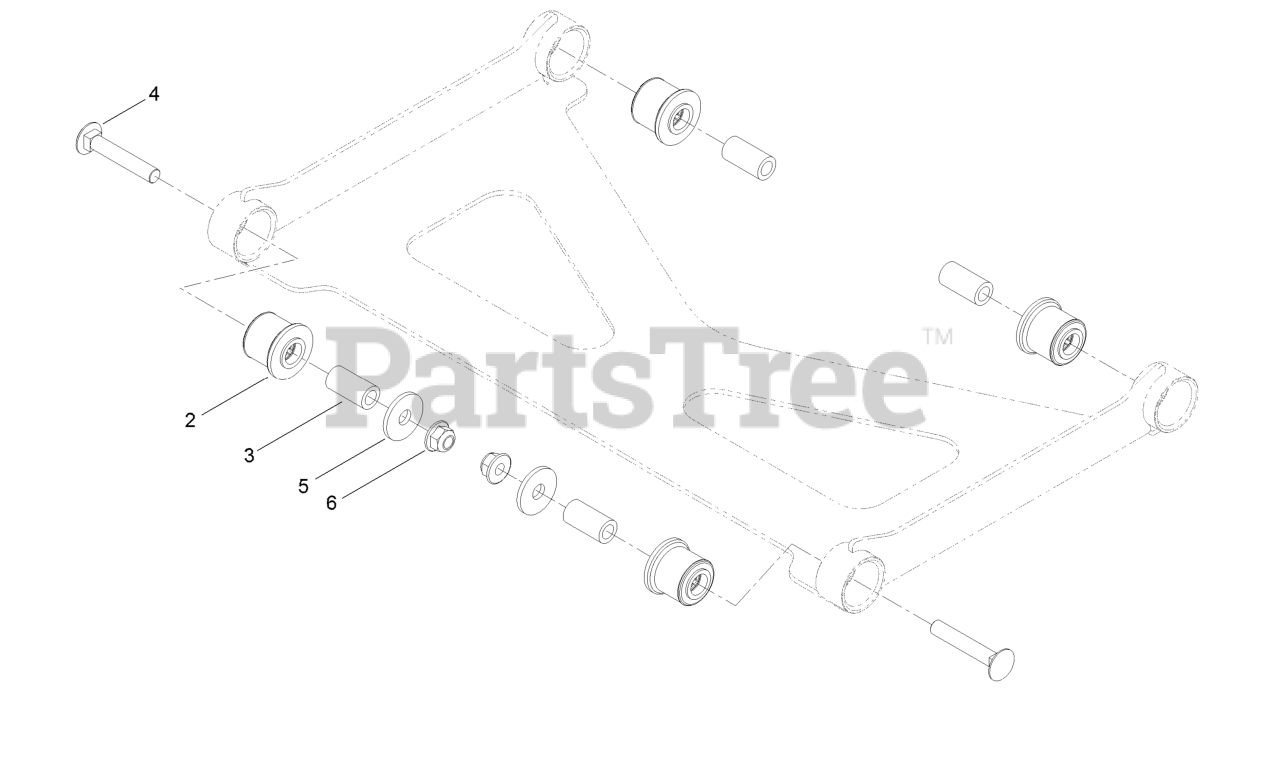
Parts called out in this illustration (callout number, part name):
2	Bushing-Rubber, Suspension
4	Screw-CARR
5	Washer
6	Nut-HF, NI
